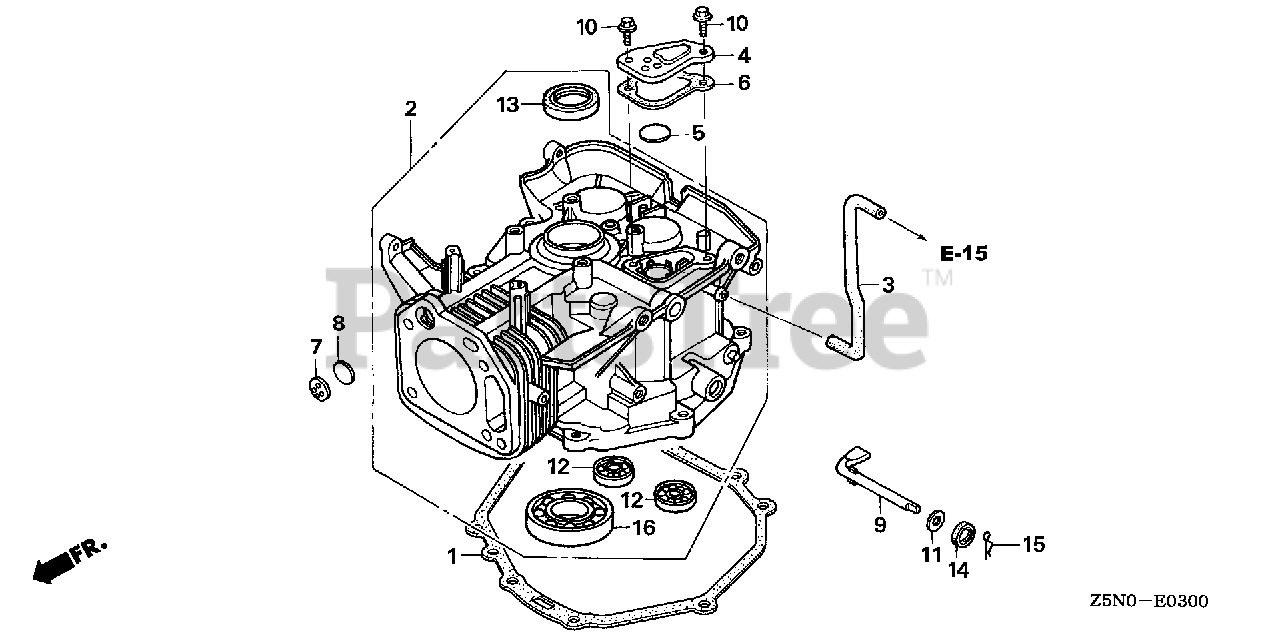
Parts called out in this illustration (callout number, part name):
1	GASKET, OIL PAN
2	CYLINDER ASSY.
3	TUBE, BREATHER
4	CAP, BREATHER CHAMBER
5	VALVE, BREATHER
6	GASKET, BREATHER CAP
7	PLATE, ONE-WAY VALVE
8	VALVE, ONE-WAY
9	SHAFT, GOVERNOR ARM
10	BOLT, FLANGE (6X12) (CT200)
11	WASHER, THRUST (8.1MM)
12	BEARING, RADIAL BALL (6202)
13	OIL SEAL (35X52X8) (NOK)
14	OIL SEAL (8X14X5)
15	PIN, LOCK (10MM)
16	BEARING, RADIAL BALL (6207)
